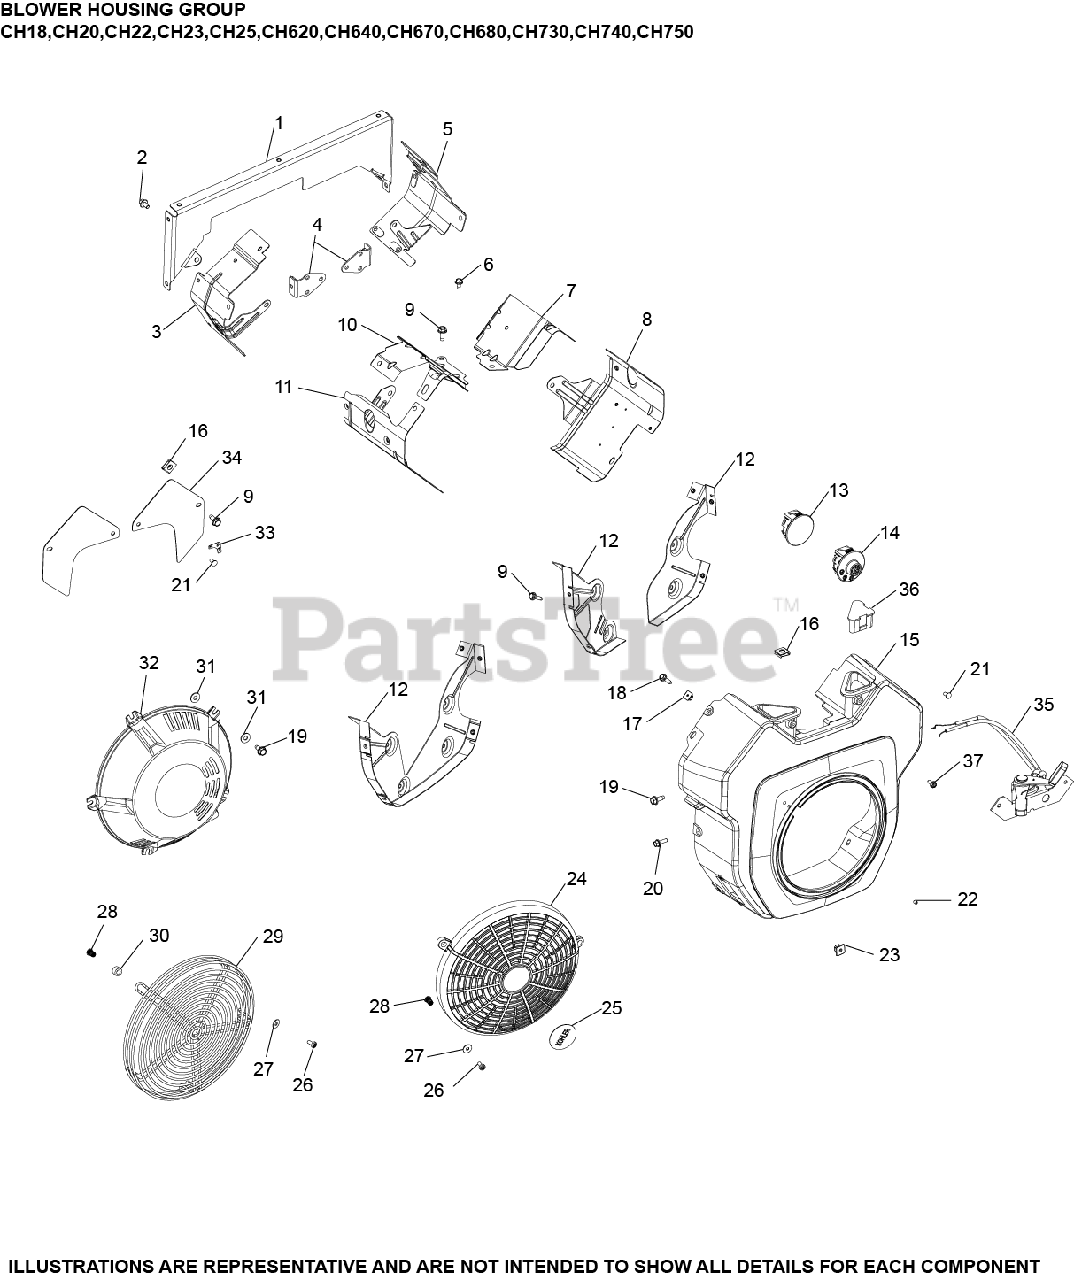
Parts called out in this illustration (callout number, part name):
6	SCREW, THREAD FORMING
7	BAFFLE, VALLEY #1 CYLINDER
8	KIT, CYL BAFFEL #1 SIDE
9	SCREW, THREAD FORMING
10	BAFFLE, VALLEY #2 CYLINDER
11	KIT, CYL BAFFEL #2 SIDE
12	KIT, BACKING PLATE
15	KIT, BLOWER HOUSING ASSEMBLY USE 24 027 448-S
16	CLIP, BAFFLE MOUNTING USE 25 154 37-S
19	SCREW, THREAD FORMING
34	KIT, ACCESS PANEL
